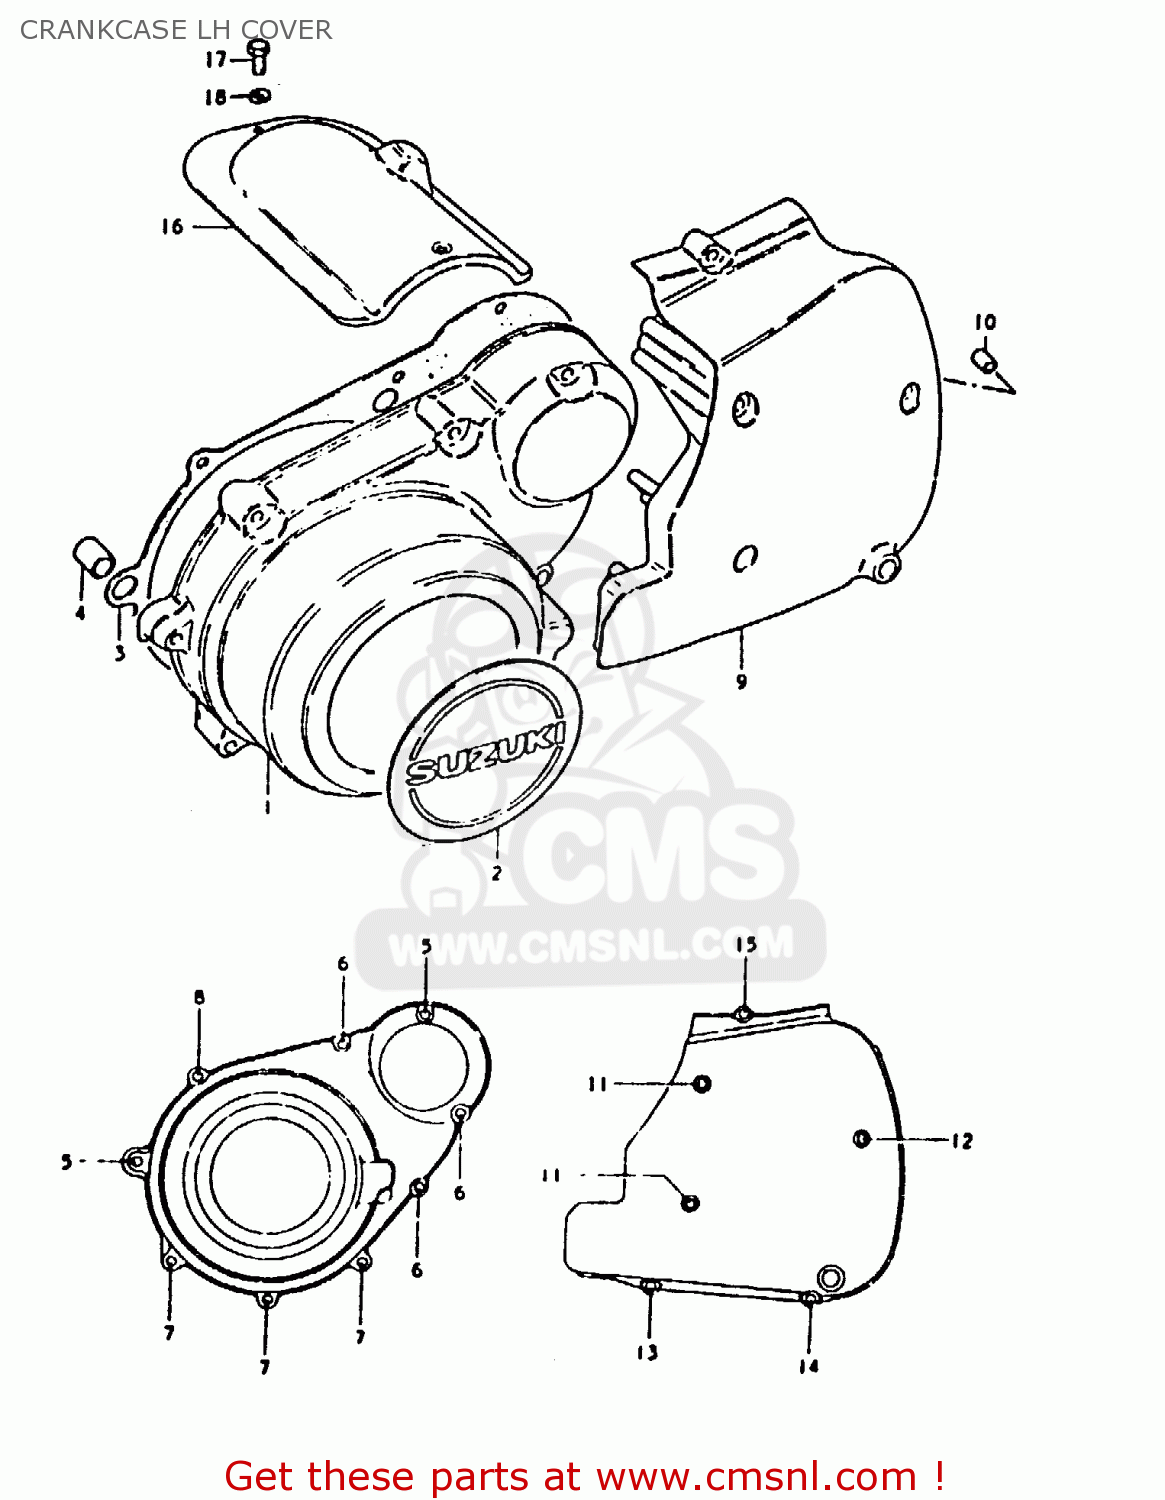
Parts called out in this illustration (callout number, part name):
1	COVER
2	EMBLEM
3	GASKET,MAGNETO COVER (MCA)
4	PIN
5	SCREW (6X45)
6	SCREW
7	SCREW (6X35)
8	SCREW
9	COVER,ENGINE SPROCKET
10	PIN
11	SCREW(6X100)
12	SCREW 6X85
13	SCREW 6X70
14	SCREW
15	SCREW
16	COVER,STARTER MOTOR
17	BOLT
18	WASHER
